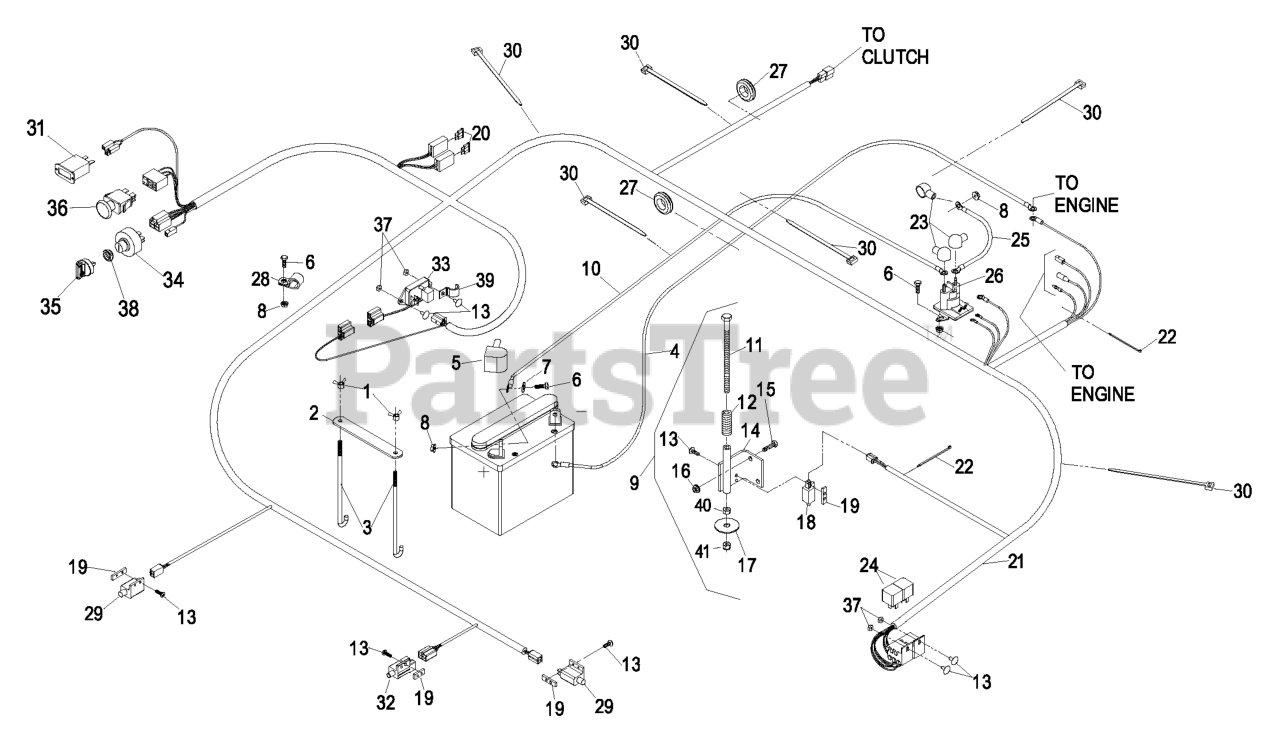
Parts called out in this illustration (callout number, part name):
1	WINGNUT
2	STRAP-HOLDDOWN, BATTERY
3	BOLT-HOLDDOWN
4	CABLE-GROUND, NEGATIVE
6	SCREW-HH
7	WASHER-FLAT
9	ASM,SEAT SWITCH ACTUATOR
11	SCREW-HH
12	SPRING-SWITCH, SEAT
13	SCREW-PPH
14	BRACKET-SWITCH, SEAT
15	SCREW-HH
18	SWITCH-CLOSED, NORMALLY
19	PLATE-TAPPED
20	FUSE-BLADE TYPE, 20 AMP
21	HARNESS,WIRE LCT BV
22	TIE-CABLE
23	INSULATOR-SOLENOID
27	GROMMET
28	CLIP-LOOM
29	SWITCH-OPEN, NORMALLY
30	TIE-PLASTIC
31	METER-HOUR
33	MODULE-DELAY, SEAT
35	KEY-IGNITION
36	SWITCH-PTO
37	NUT-LOCK, NI
38	NUT-SWITCH, IGNITION
39	CLIP-HALF, LOOM
40	NUT-HEX
41	NUT-LOCK, NI
